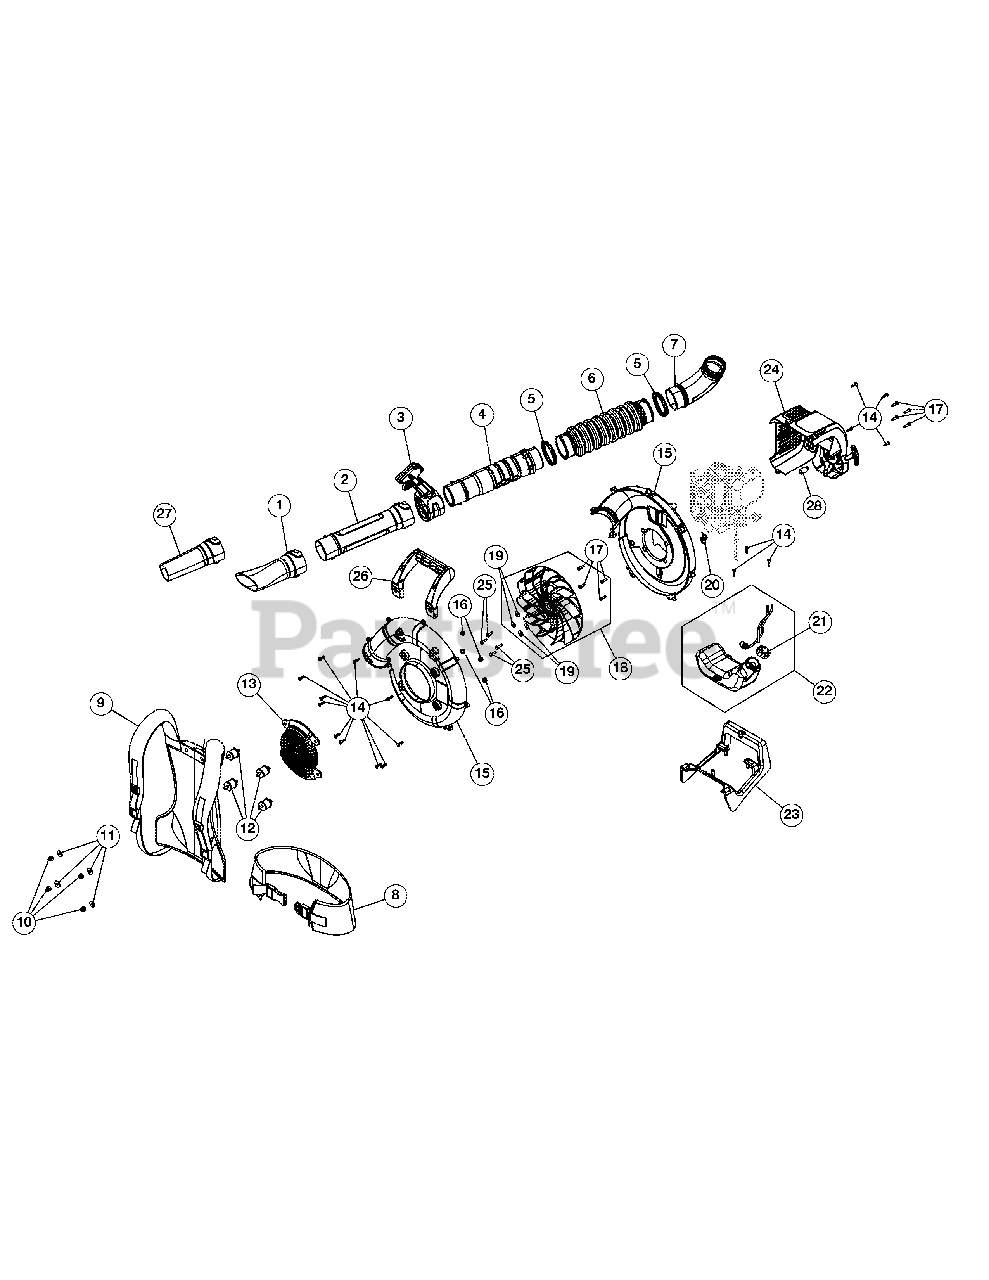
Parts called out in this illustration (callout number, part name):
1	Flared Nozzle
2	Lower Blower Tube
3	Throttle Grip Assembly
4	Upper Blower Tube
6	Flex Tube
7	Elbow Tube
8	Hip Belt
9	Support System
10	Nut
11	Washer
12	Isolator Mount
13	Intake Cover
15	Impeller Housing Assembly
17	Housing Screw
18	Impeller (Incl. 19 & 25)
20	Throttle Retaining Clip
21	Fuel Cap
22	Fuel Tank Assembly (Incl. 21)
24	Engine Cover Assembly
25	Impeller Screw
27	Concentrator Nozzle
28	Electric Starter Adapter
